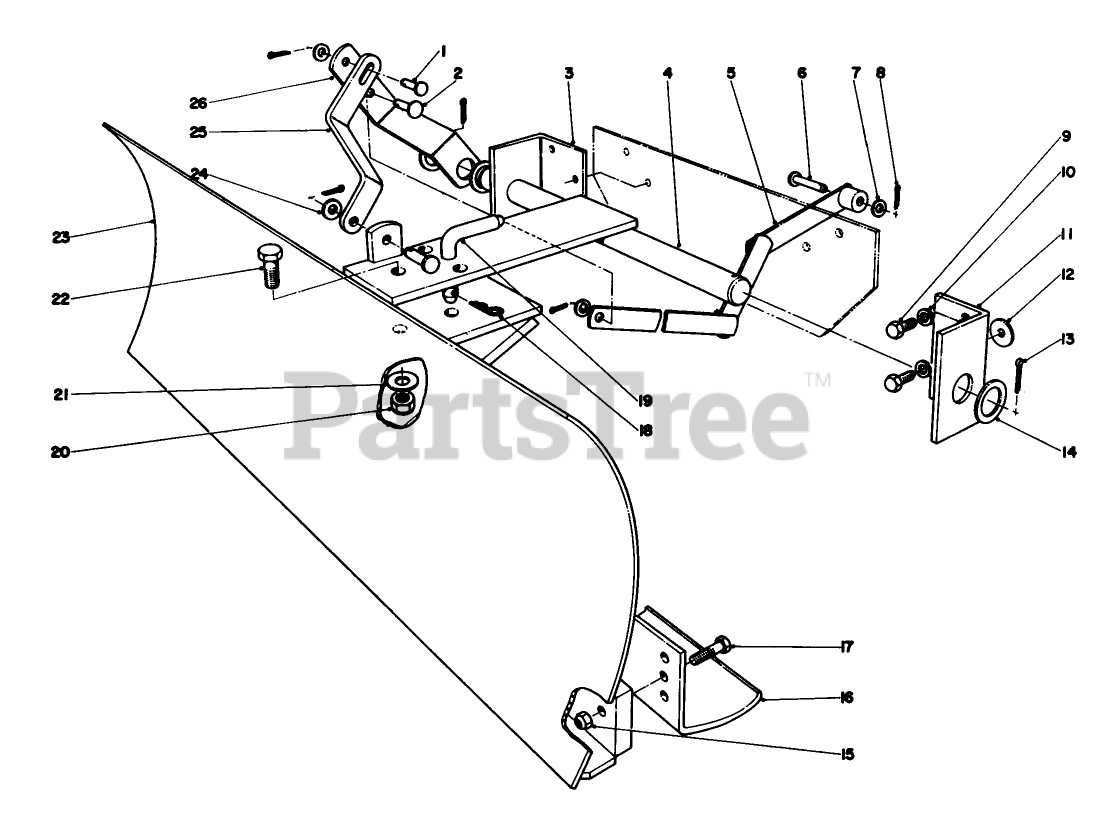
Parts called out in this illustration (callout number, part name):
3	Blade Bracket
4	Blade Hitch
5	Snow Blade Control Arm Assy.
7	WASHER-FLAT
8	PIN-COTTER
9	SCREW-HH
10	WASHER-LOCK
11	Blade Bracket
12	Washer
13	Cotter Pin
14	Washer
15	NUT-LOCK, CONE
17	SCREW-HH
18	PIN-COTTER, HAIR
19	Pivot Pin
21	WASHER-FLAT
22	SCREW-HH
23	Blade Assembly
25	Arm-Left
26	Brace
